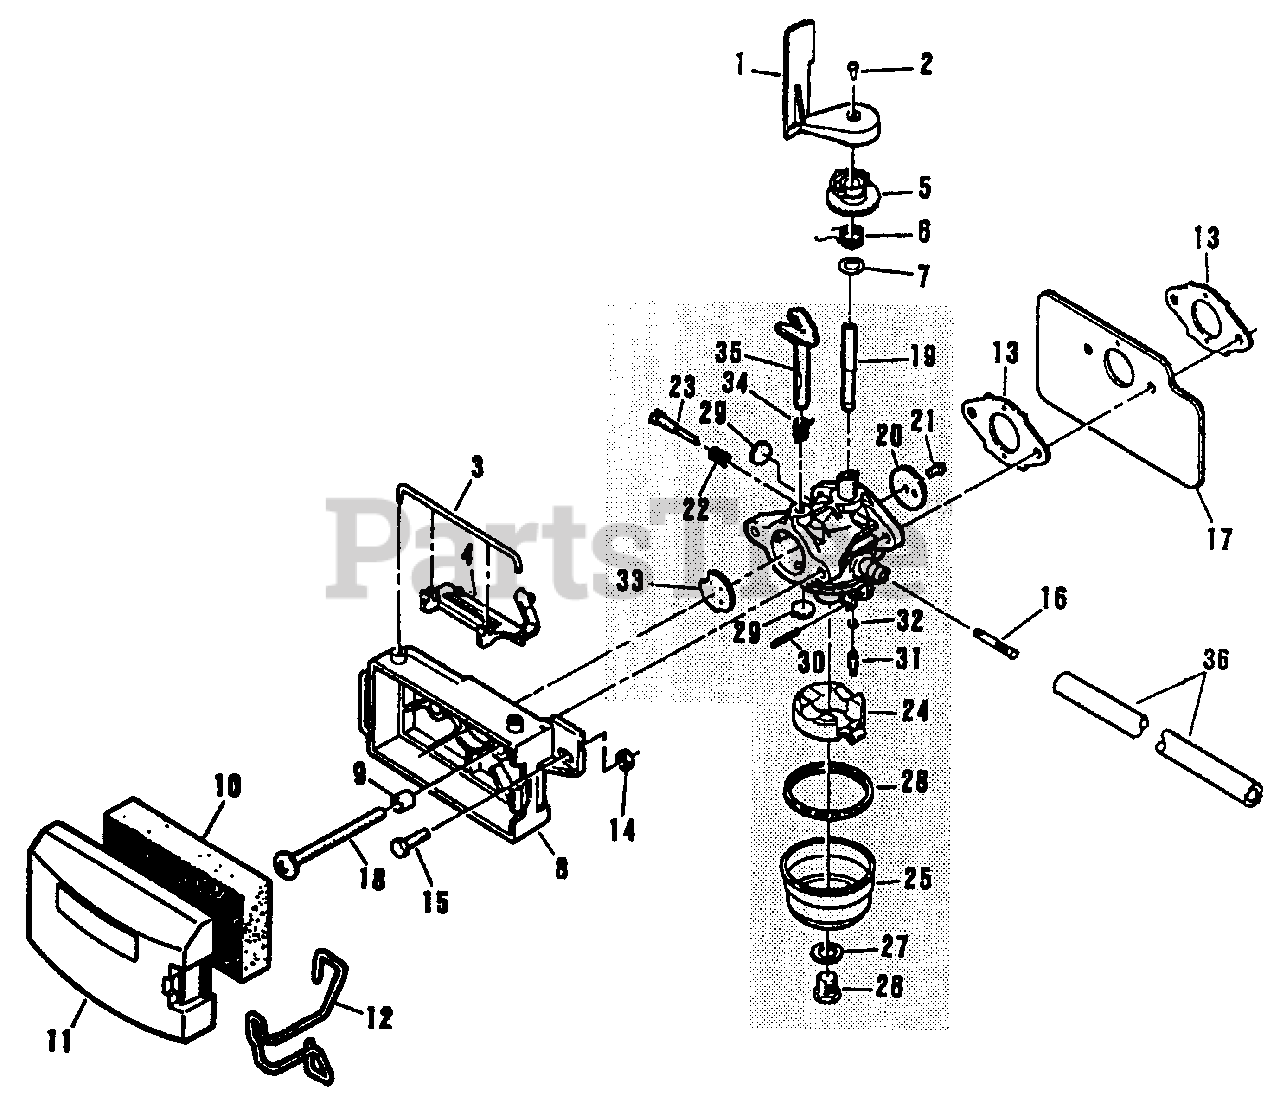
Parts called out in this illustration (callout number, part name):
1	Air Vane
2	Screw-Air Vane
3	Retainer-Speed Control Lever
4	Governor Control Lever
5	Collar
6	Spring
7	Washer
8	Air Filter Base
9	Spacer-Air Filter Base
10	Air Filter Element
11	Air Filter cover
12	Retainer-Air Filter Cover
13	Gasket
14	Nut, Hex-Throttle Cable
15	Screw-Throttle Cable
16	Fuel Filter
17	Heat Shield
18	Screw-Carburetor Mounting
19	Throttle Shaft
20	Throttle Plate
21	Screw-Throttle Plate
22	Spring-Idle Needle
23	Idle Needle
24	Float Assembly Kit
25	Fuel Bowl
26	Screw-Bowl Retainer
27	Bowl Retainer Gasket
28	Fuel Bowl Gasket
29	Plug-Welch
30	Float Shaft
31	Inlet Needle Valve
32	Valve Seat
33	Choke Plate
34	Choke Return Spring
35	Choke Shaft
36	Fuel Line
